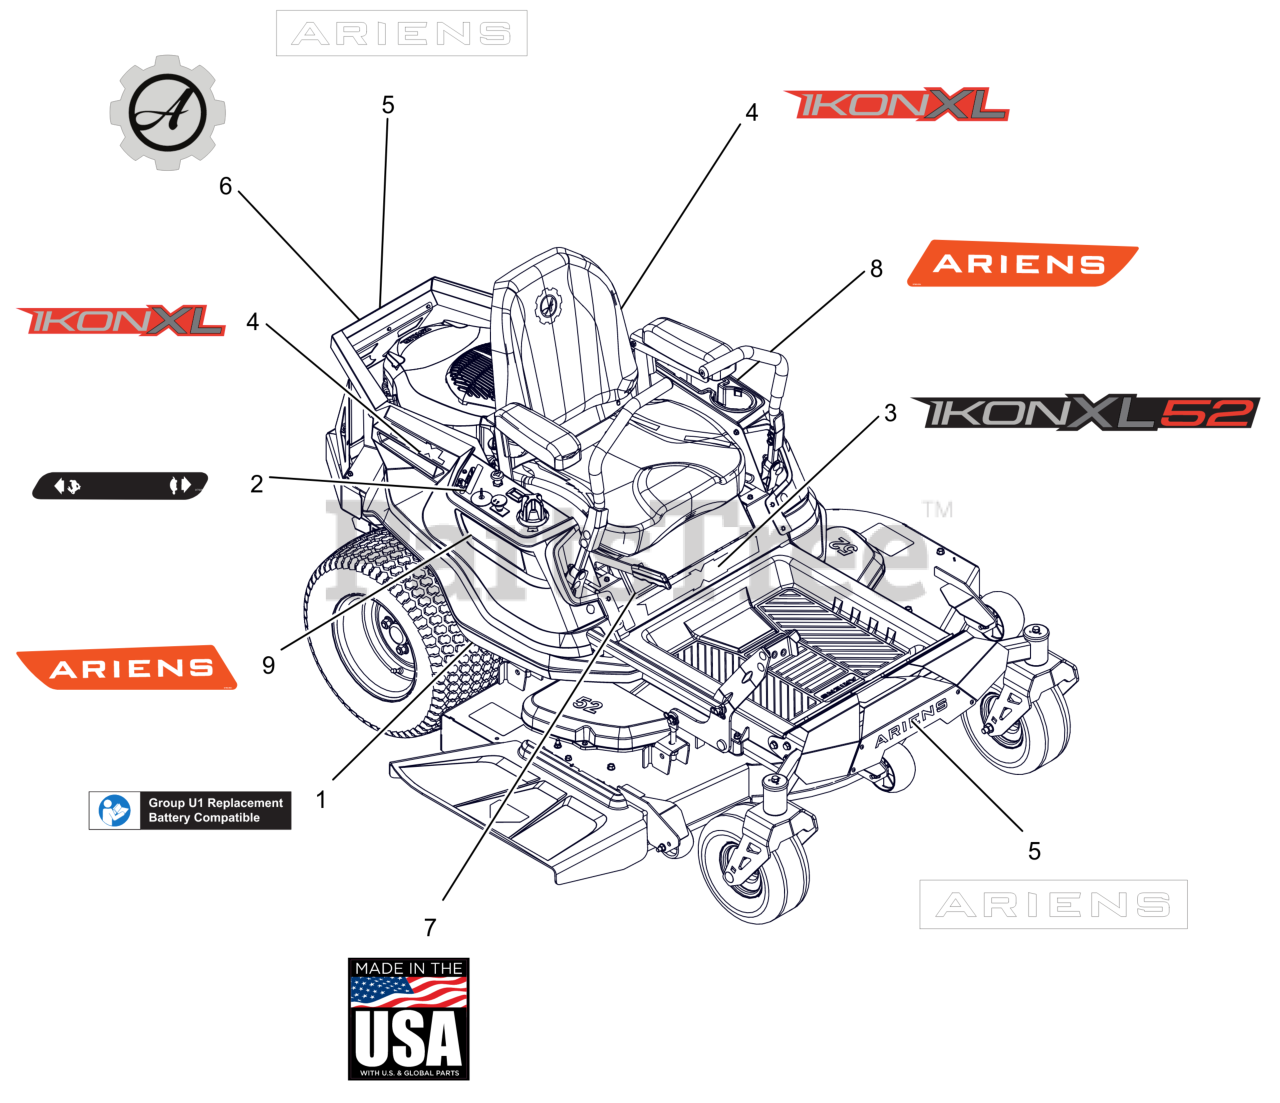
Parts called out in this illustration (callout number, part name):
1	DECAL, U1 BATTERY REPLACEMENT
2	DECAL, DASH DECAL
3	DECAL, IKON-XL 52"
4	DECAL, IKON-XL
5	DECAL - ARIENS 9.625"
6	DECAL, ARIENS-GEAR BADGE -THK
7	DECAL, MADE IN USA
8	DECAL, FENDER LH
9	DECAL, FENDER RH
